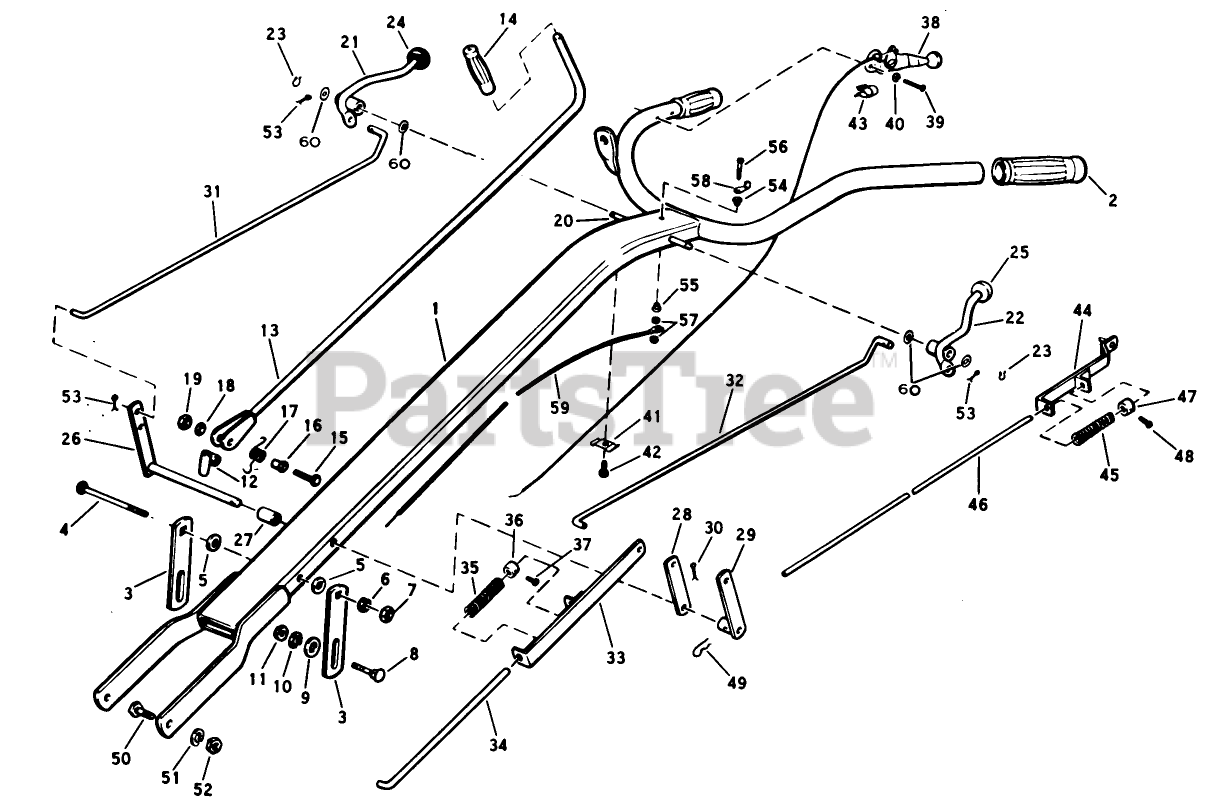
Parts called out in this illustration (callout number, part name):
1	Handle Bar Assembly
6	Lockwasher
7	Hex Nut 3/8-16
8	Carriage Bolt 7/16-14 x 1-1/4 Lg.
9	Washer 7/16
11	Hex Nut 7/16-14
12	Shift Rod Bearing Assembly
13	Hand Shift Rod Assembly
15	Hex Head Capscrew 3/8-16 x 1-3/4 Lg.
21	Control Handle Assembly RH
22	Control Handle Assembly LH
23	Retaining Ring Truarc 5555-37
26	Implement Control Lever and Shaft Assembly
28	Transmission Control Lever Assembly
29	Implement Lever Assembly
32	Control Rod Assembly LH
33	Spring Bracket Assembly
34	Control Spring Rod
35	SRV BULLT 437B
37	Set Screw
38	Throttle Control Assembly
39	Battery 308, 310, 312-s, 414
40	Lockwasher #10
42	Sheet Metal Screw 1/4-20 x 7/16 Lg.
43	Cable Clip
44	Spring Bracket and Pin Assy
48	Set Screw
50	Hex Head Capscrew 3/8-16 x 1-1/2 Lg.
51	Lockwasher
52	Hex Nut 3/8-16
53	Cotter Pin
54	Insulating Washer (fiber)
55	Washer (fiber)
56	Control Handle Assembly RH
57	Hex Nut #8-32
59	Shut Off Wire Assembly 54-1/2 Lg.
